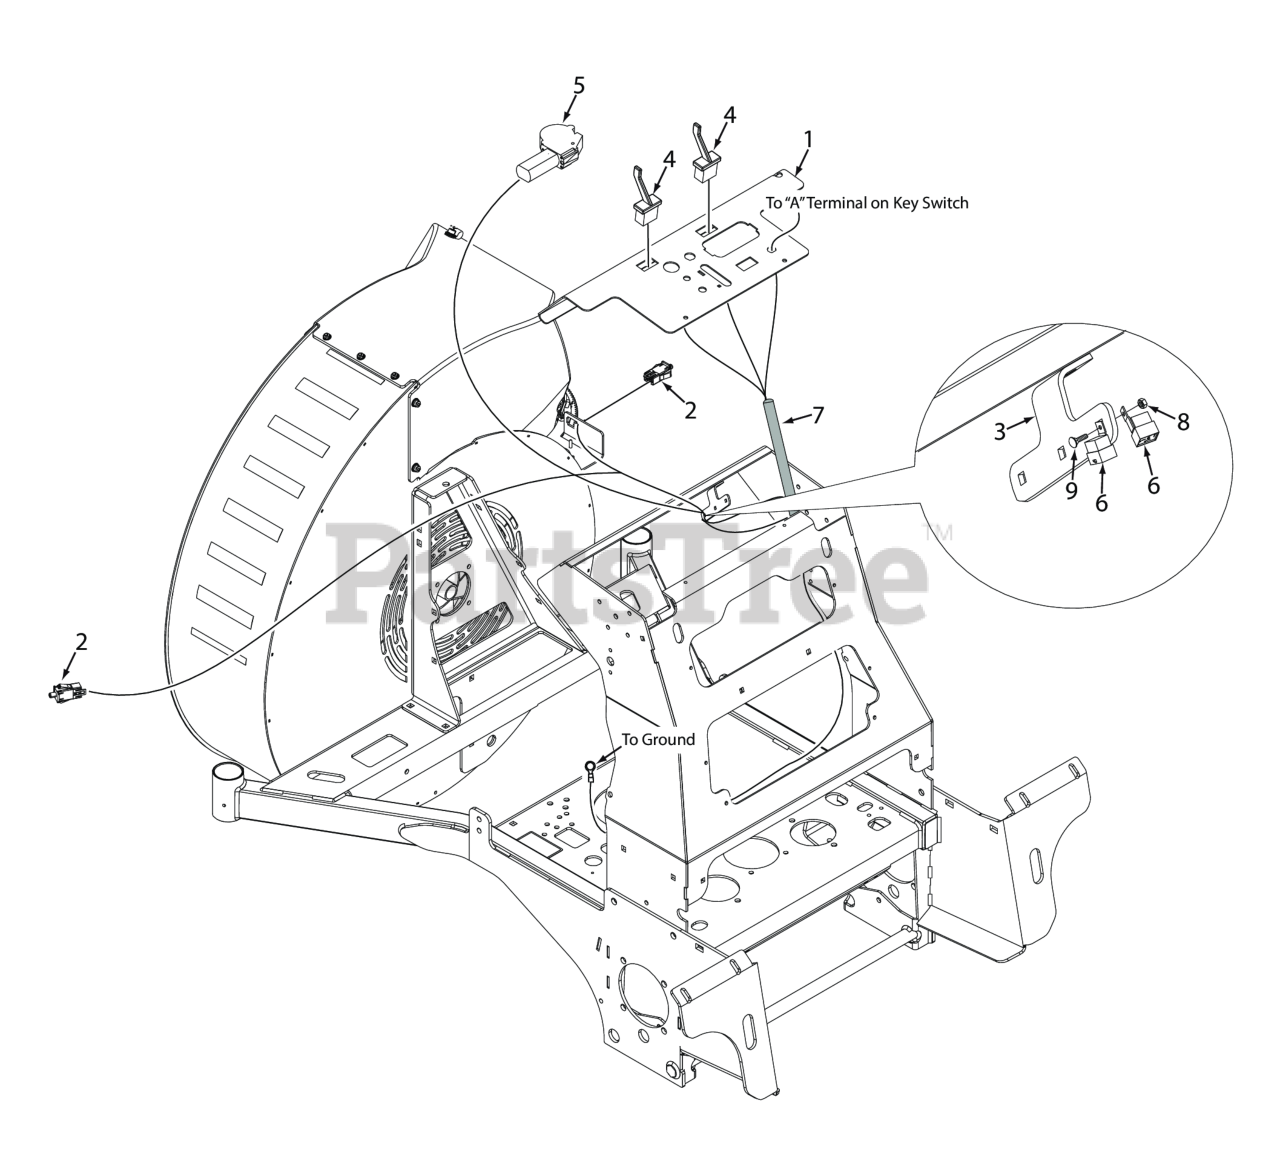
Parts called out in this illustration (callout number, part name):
1	Control Panel w/Decals
2	Switch, Plunger, Double Pole, Snap
3	Mounting Bracket, Relays
4	Switch, Nozzle Direction
5	Motor, Gear Drive
6	Relay, 12V 40 AMP Standard
7	Wire Harness, Nozzle Control
8	Nut, Elastic Stop #10-24
9	Bolt, Carriage #10-24 x 1/2"
